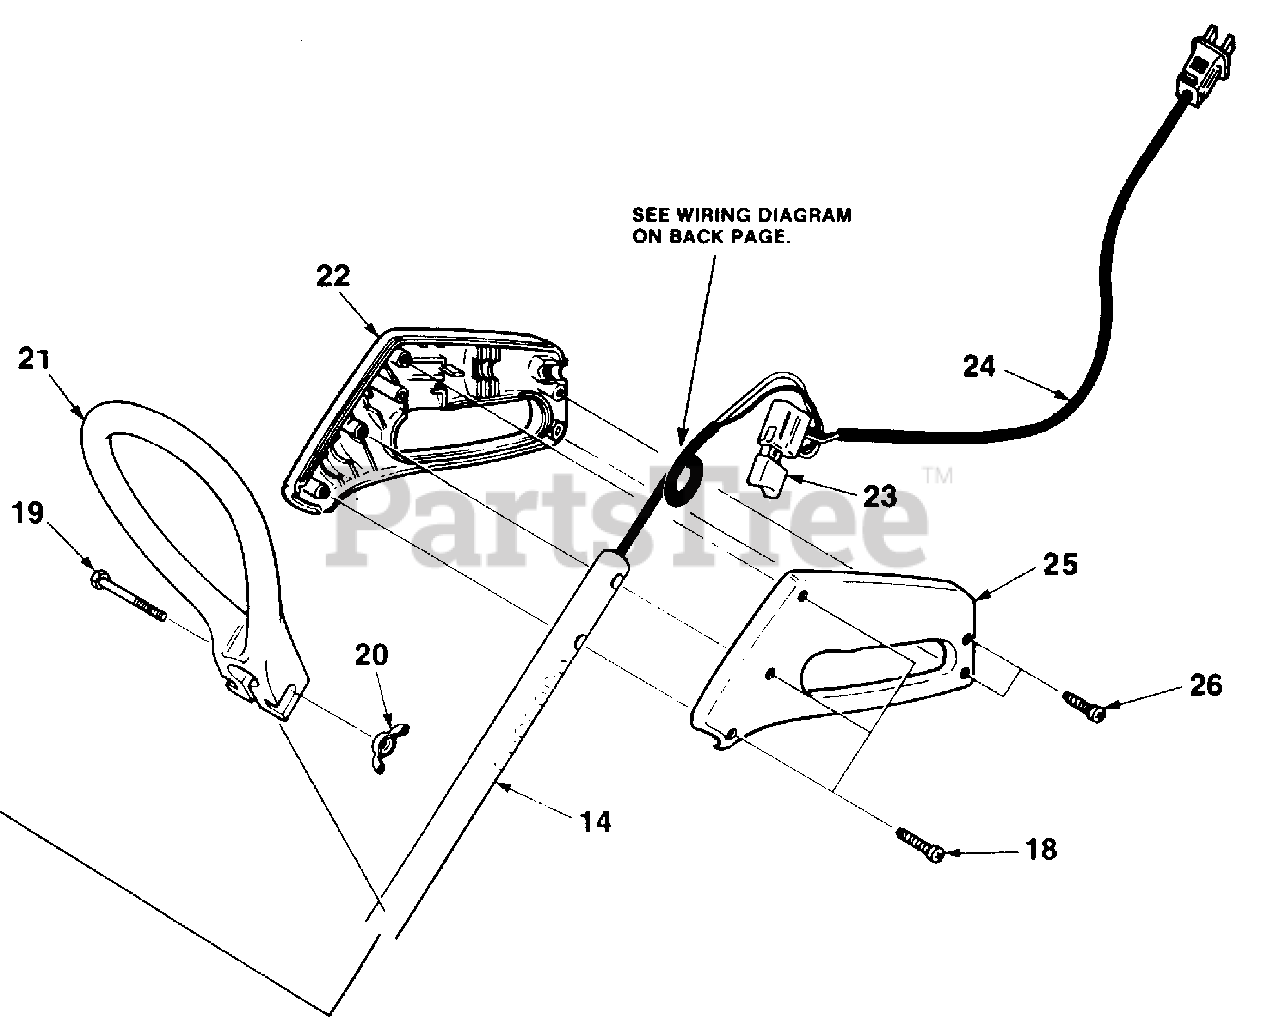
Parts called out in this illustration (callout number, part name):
18	SCREW- Thread forming (10 x 1")
19	SCREW- Cap hex hd. 1/4-20 x 2
20	NUT- Wing washer face
21	HANDLE- Front
22	HANDLE- Right side
24	CORD SET
25	HANDLE- Left side
26	SCREW- Thread forming (10-16 x 9/16)
